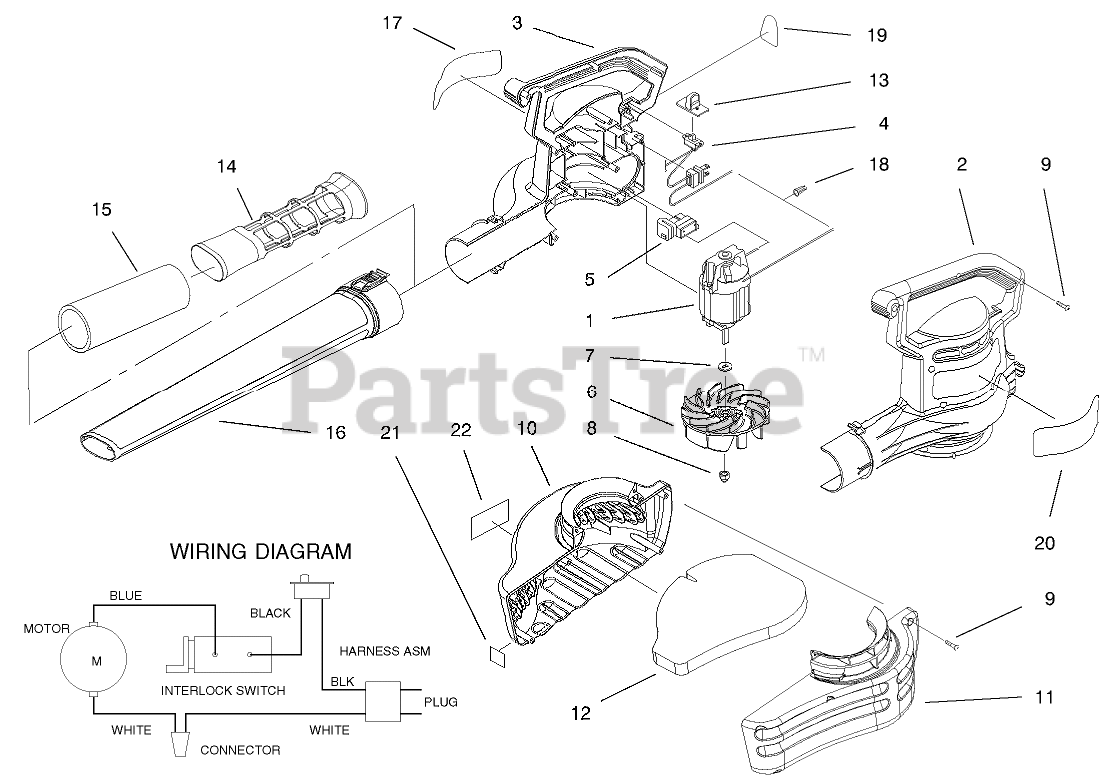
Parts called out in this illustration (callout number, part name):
1	MOTOR - ELECTRIC, 120 V
2	Housing-L.H.
3	Housing-R.H.
4	HARNESS ASSEMBLY
5	SWITCH - INTERLOCK
6	IMPELLER - BLOWER
7	WASHER
8	NUT-HEX
9	SCREW-PPH
10	INLET - QUIET, RH
11	INLET - QUIET, LH
12	FOAM - INLET
13	COVER - SWITCH, RED
14	INSERT - QUIET
15	FOAM - INSERT
16	TUBE-BLOWER LONG
17	Decal-Warning
18	CONNECTOR-NUT, WIRE
19	DECAL - INFORMATION
20	DECAL, LOGO, SUPRBLWR
21	DECAL - 63DBA
22	DECAL - QUIETECH
